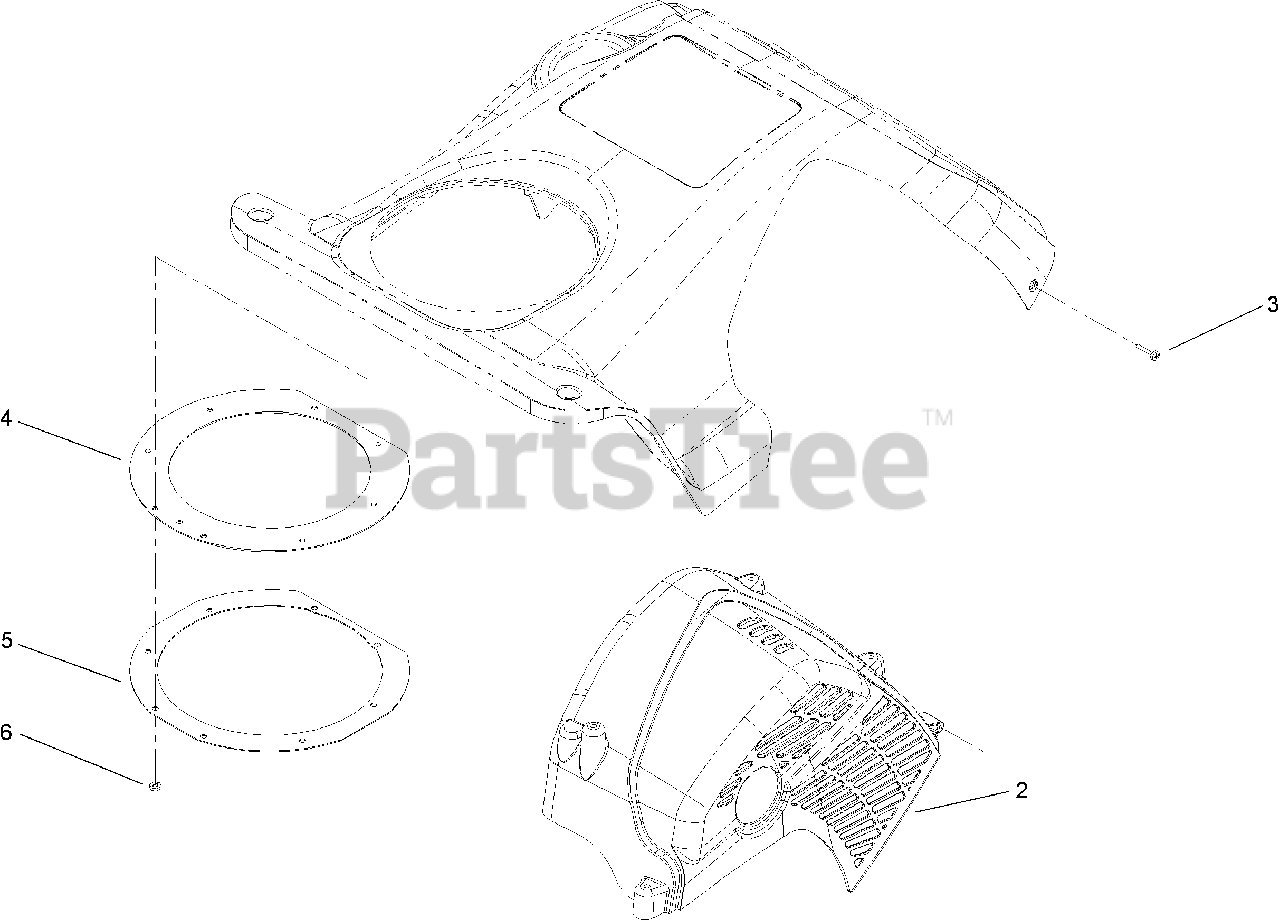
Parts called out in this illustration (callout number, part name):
2	SHIELD-HEAT
3	SCREW-PPH
4	Seal-Chute
5	RETAINER-SEAL, CHUTE
